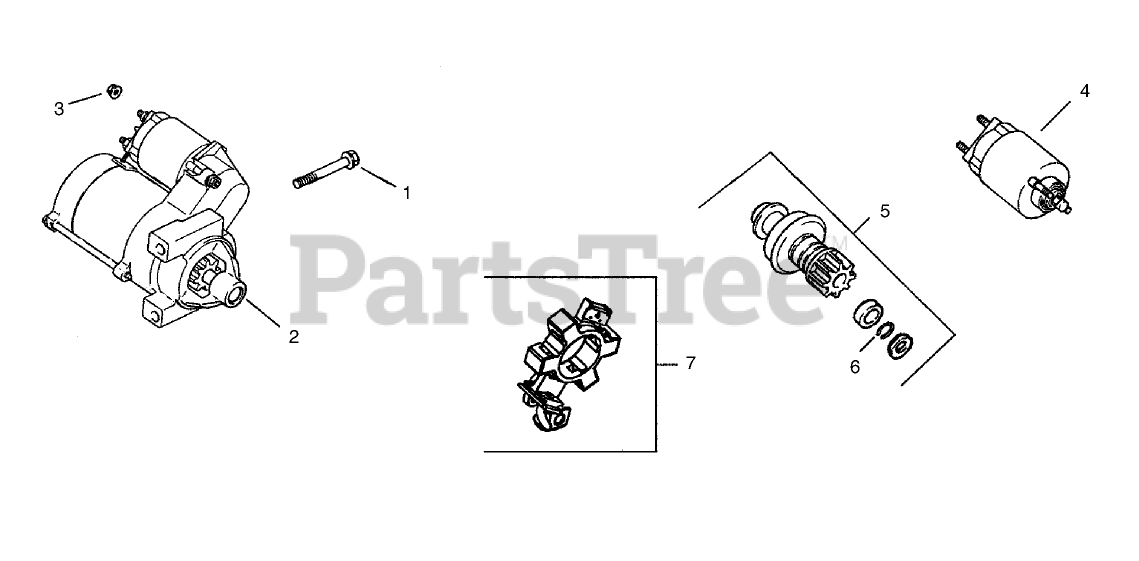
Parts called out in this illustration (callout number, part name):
1	SCREW-FLG (M8X1.25X80)
2	STARTER ASM (SOLENOID SHIFT)
3	NUT-FLANGE (M8X1.25)
4	Solenoid Kit
5	STARTER PINION DRIVE KIT
7	BRUSH HOLDER KIT
